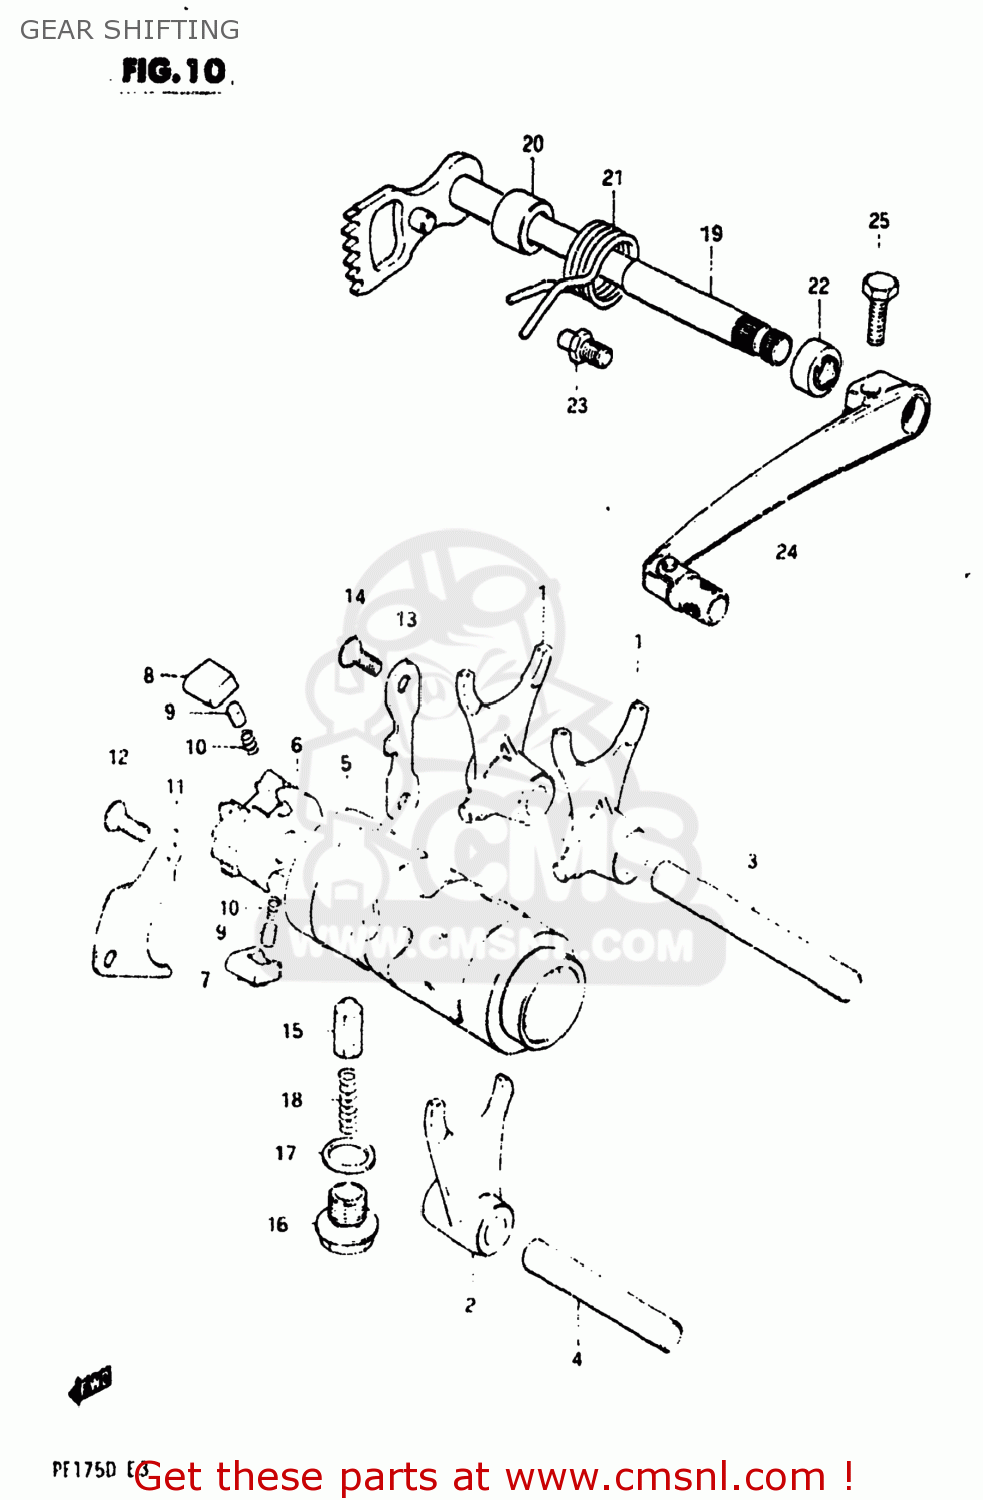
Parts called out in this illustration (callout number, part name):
1	FORK,GEAR SHIFT NO.1
2	FORK,GEAR SHIFT NO.2
3	SHAFT,GEAR SHIFT FORK
4	SHAFT,GEAR SHIFT FORK
5	CAM,GEAR SHIFT
6	RETAINER,GEAR SHIFT CAM
7	PAWL,GEAR SHIFT NO.1
8	PAWL,GEAR SHIFT NO.2
9	PIN(5X8)
10	SPRING
11	LIFTER,GEAR SHIFT PAWL
12	SCREW
13	GUIDE,GEAR SHIFT CAM
14	SCREW
15	STOPPER,GEAR SHIFTING
16	BOLT,GEAR SHAFT CAM STOPPER
17	GASKET(14X19.2X2) (NAS)
18	SPRING
19	SHAFT,GEAR SHIFT
20	SPACER(12X20X15.3)
21	SPRING
22	OIL SEAL
23	STOPPER,GEAR SHIFT CAM
24	LEVER,GEAR SHIFT
25	BOLT
